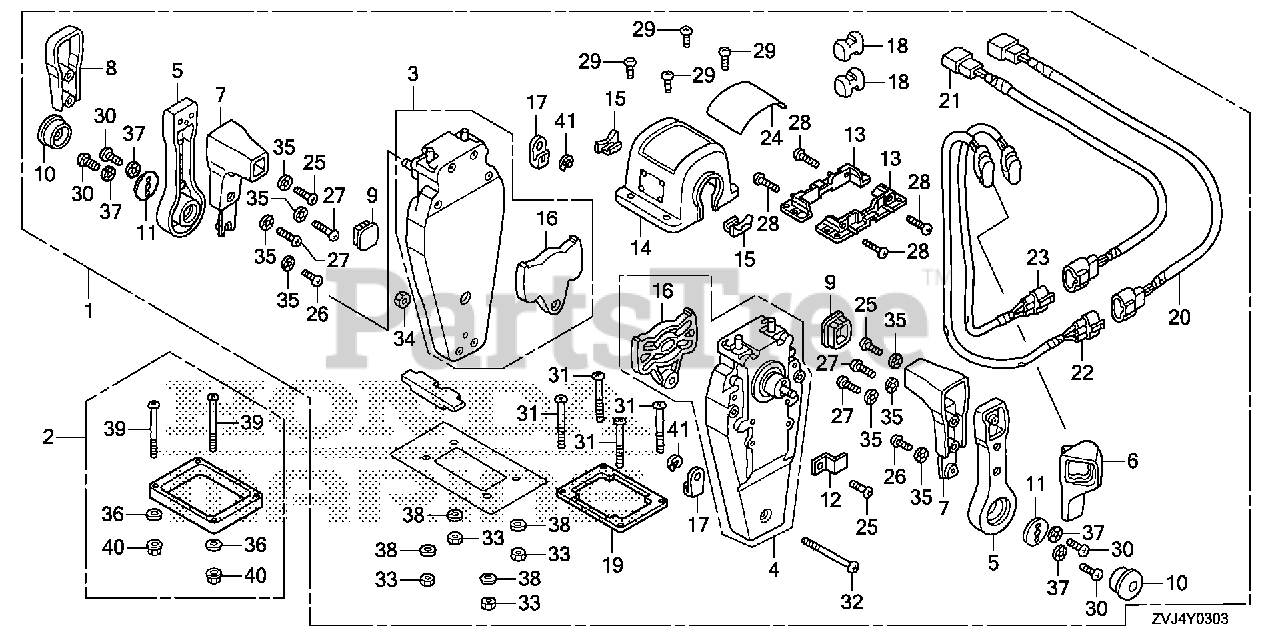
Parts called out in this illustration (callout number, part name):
1	BOX KIT, REMOTE CONTROL (TOP MOUNT DUAL)(L)
2	SPACER KIT, REMOTE CONTROL BOX (TOP MOUNT DUAL)
3	HOUSING ASSY., L. (INNER) (TOP MOUNT)
4	HOUSING ASSY., R. (INNER) (TOP MOUNT)
5	HANDLE, REMOTE CONTROL
6	COVER, R. GRIP
7	GRIP, REMOTE CONTROL HANDLE
8	COVER, DUAL GRIP
9	CAP, GRIP
10	BUTTON, THROTTLE
11	PLATE, HANDLE
12	PLATE, CABLE CLAMP
13	BRACKET, REMOTE CONTROL HOUSING
14	HOUSING, DUAL REMOTE CONTROL BOX
15	HOUSING, LEAD
16	PLATE, DWELL
17	TERMINAL, CABLE
18	SPACER, CABLE CLAMP
19	GASKET, DUAL
20	SUB-HARNESS ASSY., POWER TRIM-TILT (A)
21	SUB-HARNESS ASSY., POWER TRIM-TILT (B)
22	SWITCH ASSY., POWER TRIM-TILT (A)
23	SWITCH ASSY., POWER TRIM-TILT (B)
24	MARK, REMOTE CONTROL (DUAL)
25	SCREW, PAN (5X16)
26	SCREW, PAN (5X10)
27	SCREW, PAN (5X20)
28	SCREW, PAN (5X18)
29	SCREW, PAN (4X10)
30	SCREW, PAN (6X18)
31	SCREW, PAN (5X40)
32	SCREW, PAN (5X55)
33	NUT, HEX. (5MM)
34	NUT, HEX. (5MM)
35	WASHER, LOCK (5MM)
36	WASHER, PLAIN (5MM)
37	WASHER, LOCK (6MM)
38	WASHER, PLAIN (5MM)
39	SCREW, PAN (5X65)
40	NUT, HEX. (5MM)
41	E-RING (6MM)
